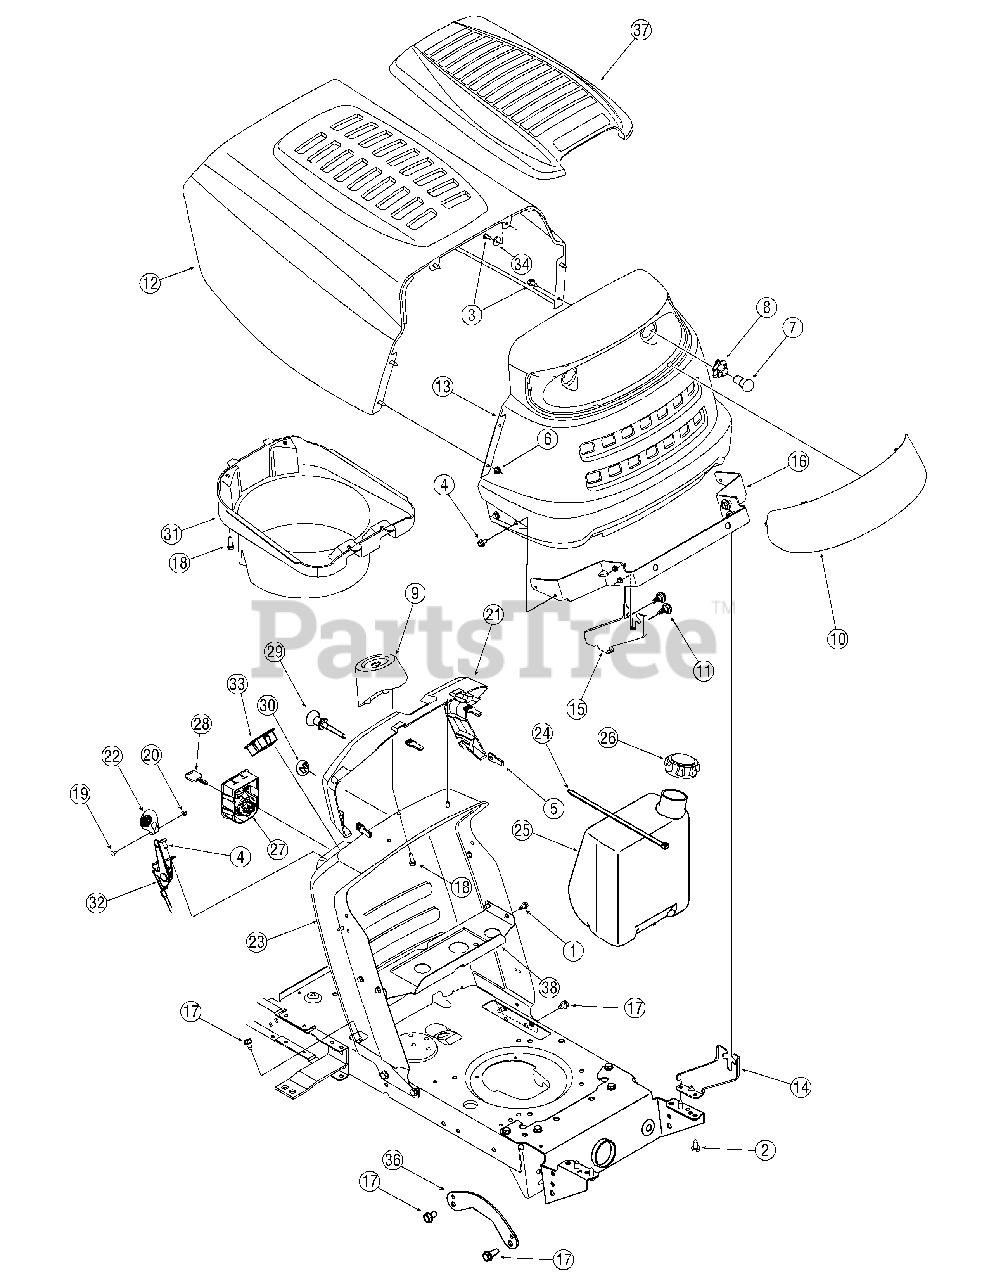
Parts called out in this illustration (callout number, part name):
1	Screw, 1/4-20, 0.500
2	Screw, 5/16-12, 0.750
3	Screw, 1/4-20, .620, Gr5
4	Screw, 1/4-20, .625
5	Nut, 1/4-20, Speed U-type
6	Nut, Flange Lock, 1/4-20, GrF, Nylon
7	Headlamp, 12V
8	Headlamp Socket
9	Support, Steering
10	Lens
11	Screw, Shoulder, .43 x.29, 5/16-18
18	Screw, 1/4-15, 0.750
19	Screw, Machine, #8-32, 0.375
20	Nut, Hex, #8-32, GrA
21	Collar, Dash
22	Knob, Control
24	Cable Tie, 34.75
25	Fuel Tank, 1.5 gal.
26	Fuel Tank Cap
27	Module, Ignition Switch
28	Key
29	Choke Control, 37.5" (if equipped)
31	Plenum (Single Cylinder Engine)
31	Plenum (Twin Cylinder Engine)
32	Throttle/Choke Control, 25" (Single Cylinder Engine)
32	Throttle Control, 39" (Twin Cylinder Engine)
33	Ammeter
34	Flat Washer .265 x .938 x .120
35	Screw, 5/16-18, 0.750
37	Hood Cover
